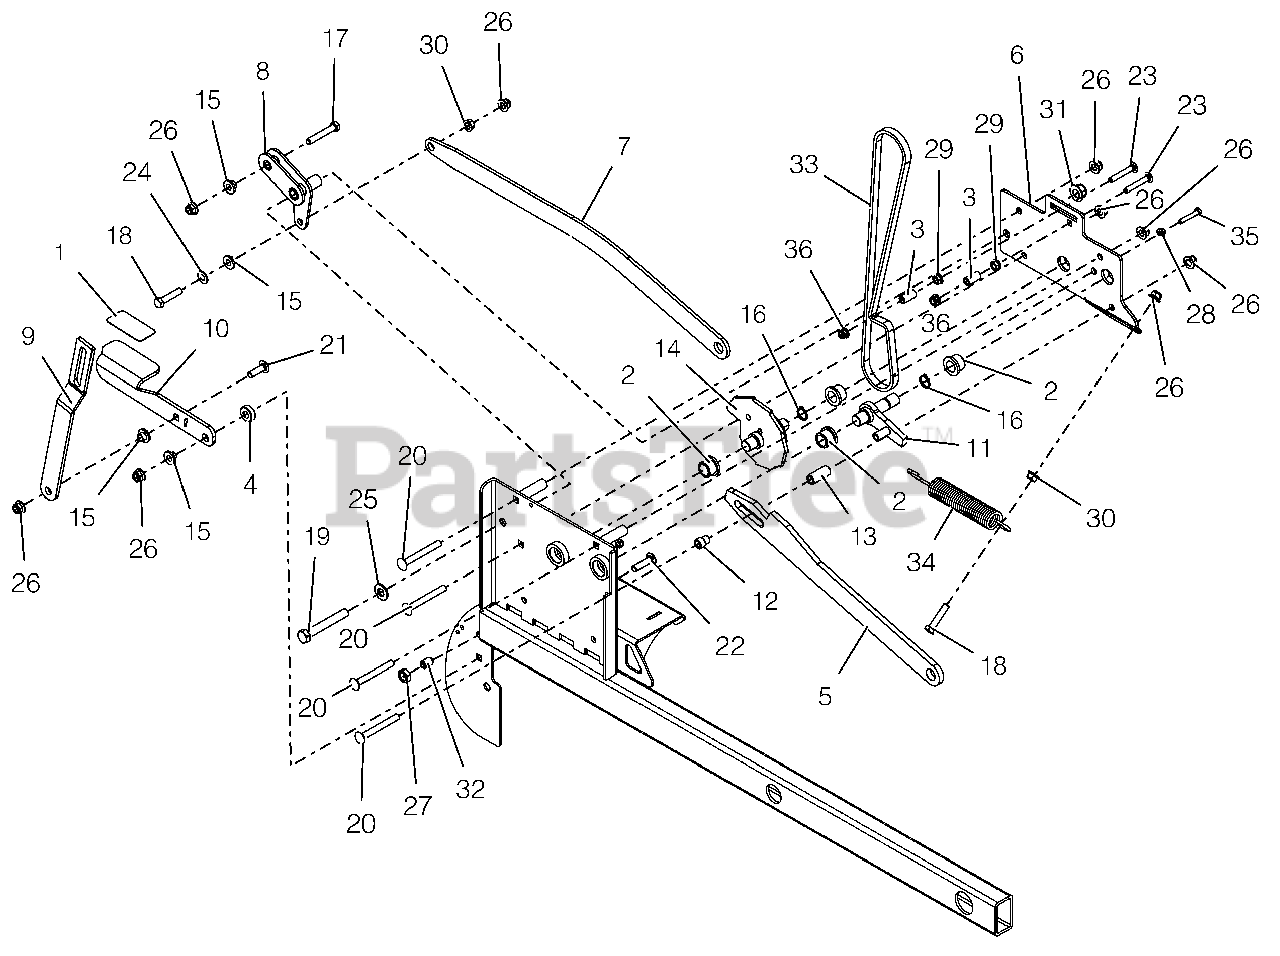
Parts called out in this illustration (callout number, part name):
1	GRIP, PEDAL 1.50 X 3.00
2	BUSHING, FLANGE .75X.75X1.0
3	SPACER .331 X .500 X 1.000
4	SPCR, .375 X 1.00 X .342
5	ARM, CAM CONTACT
6	WLDMT, CAM COVER
7	ARM, PEDAL
8	WLDMT, REAR PEDAL PIVOT
9	LINK, REAR PEDAL
10	PEDAL, DECK LIFT FOOT
11	WLDMT, TRAILER LOCK
12	BSHG, .375 X .75 X 1.00
13	SPCR, .375 X .75 X 1.00
14	WLDMT, 36 PS HOC CAM
15	BSHG-FLG .385X.500X.875X.406
16	RG-RTNG-EXT .689X.078
17	@BLT-HEX .38-16X2.25 GR5 YWZC
18	@BLT-HEX .38-16X1.75 GR5 YWZC
19	@BLT-HEX .50-13X3.50 GR5 YWZC
20	BLT-RDHDSQNK .38-16X3.25 GR5YZ
21	@BLT-RHDSSQNK .38-16X1.25 G5YZ
22	@BLT-RHDSSQNK .38-16X1.50 G5YZ
23	BLT-RDHDSQNKFT .31-18X2.0 G5YZ
24	@WSHR-FL-STL.406X.812X.065 YWZ
25	@WSHR-FL-STL.531X1.06X.095YWZC
26	@NUT-LK-NYL-FLG .38-16 YWZC
27	NUT-JAM .50-13 YWZC
28	@NUT-SPNLK-FLG .25-20 YWZC
29	@NUT-SPNLK-FLG .312-18 YWZC
30	@NUT-SPNLK-FLG .375-16 YWZC
31	@NUT-LK-NYL-FLG .50-13 YWZC
32	BALL SPRING PLUNGER, .500-13
33	BELT, TIMING SHORT
34	SG-TENS .162X1.25X8.25 WLD 25
35	@BLT-HEX .25-20X1.50 GR5 YWZC
36	@NUT-LK-NYL-FLG .31-18 YWZC
